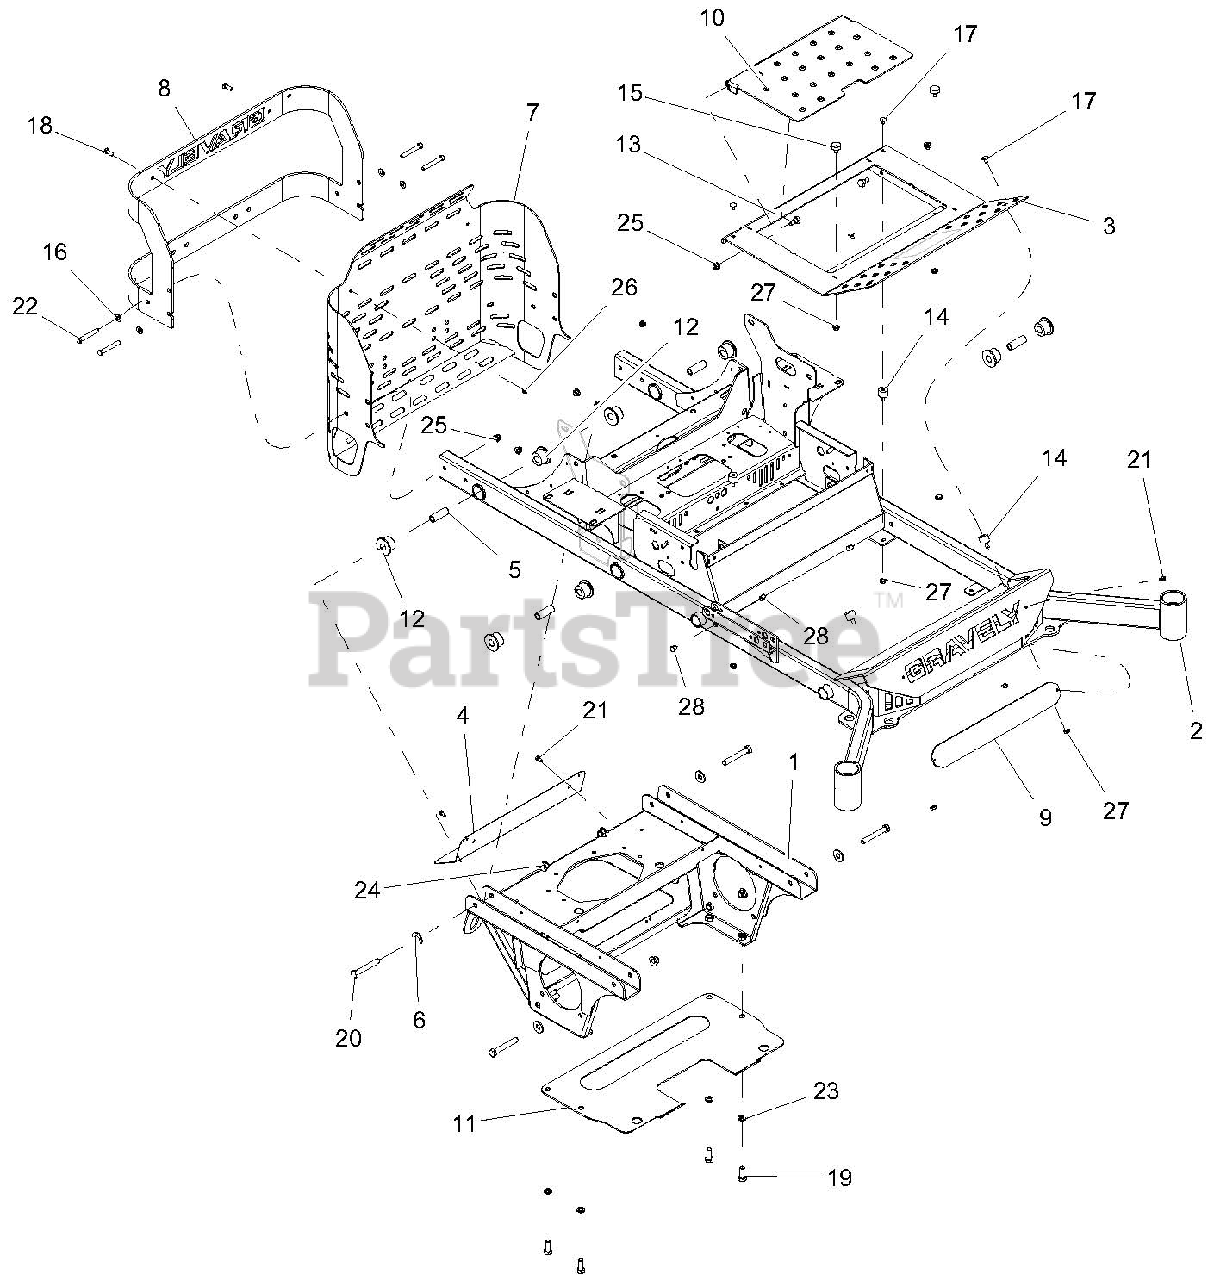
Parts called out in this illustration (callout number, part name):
1	WLDT, 200 PT AXLE/ENGINE FRAME
2	72" PT200/400 MAIN FRAME WITH SAFTEY DECALS
3	FOOTPLATE WLDMT W/SAFETY DECAL
4	SHIELD, MUFFLER HEAT
5	SPCR, .50 X .75 X 2.23 YZ
6	WSHR-FL-STL.563X1.38X.109YWZC
7	WLDMT, PT200 REAR BUMPER
8	REAR BUMPER W/SAFETY DECALS-GAS
9	PLATE, BUMPER LOGO BACKING-BLACK
10	PANEL, INSPECTION
11	PLATE-TRANSMISSION SKID-RED
12	BSHG, FLANGE .750 X 1.510 X 1.130 X 2.000
13	BLT, SHLDR EP .38-16X.30 HEX YZ
14	BUMPER, STUD MOUNTED W/FEMALE INSERT
15	BUMPER, RUBBER
16	WSHR-FL-STL.406X.812X.065 YWZ
17	BLT-RDHDSQNK .31-18X.50 G5 YWZC
18	BLT-RDHDSQSHNK .31-18X1.00 G5YWZC
19	BLT-HEX .50-13X1.25 GR5 YWZC
20	BLT-HEX .50-13X3.50 GR5 YWZC
21	SCR-TAP .25-20X.50 HWH TR YWZ
22	BLT-HEX .38-16X2.75 GR5 YWZC
23	WSHR-LK .50X.125 REG YWZC
24	NUT-LK-NYL-FLG .50-13 YWZC
25	NUT-LK-NYL-FLG .38-16 YWZC
26	NUT-LK-NYL-FLG .31-18 YWZC
27	@NUT-SPNLK-FLG .312-18 YWZC
28	PLUG, HOLE .500
